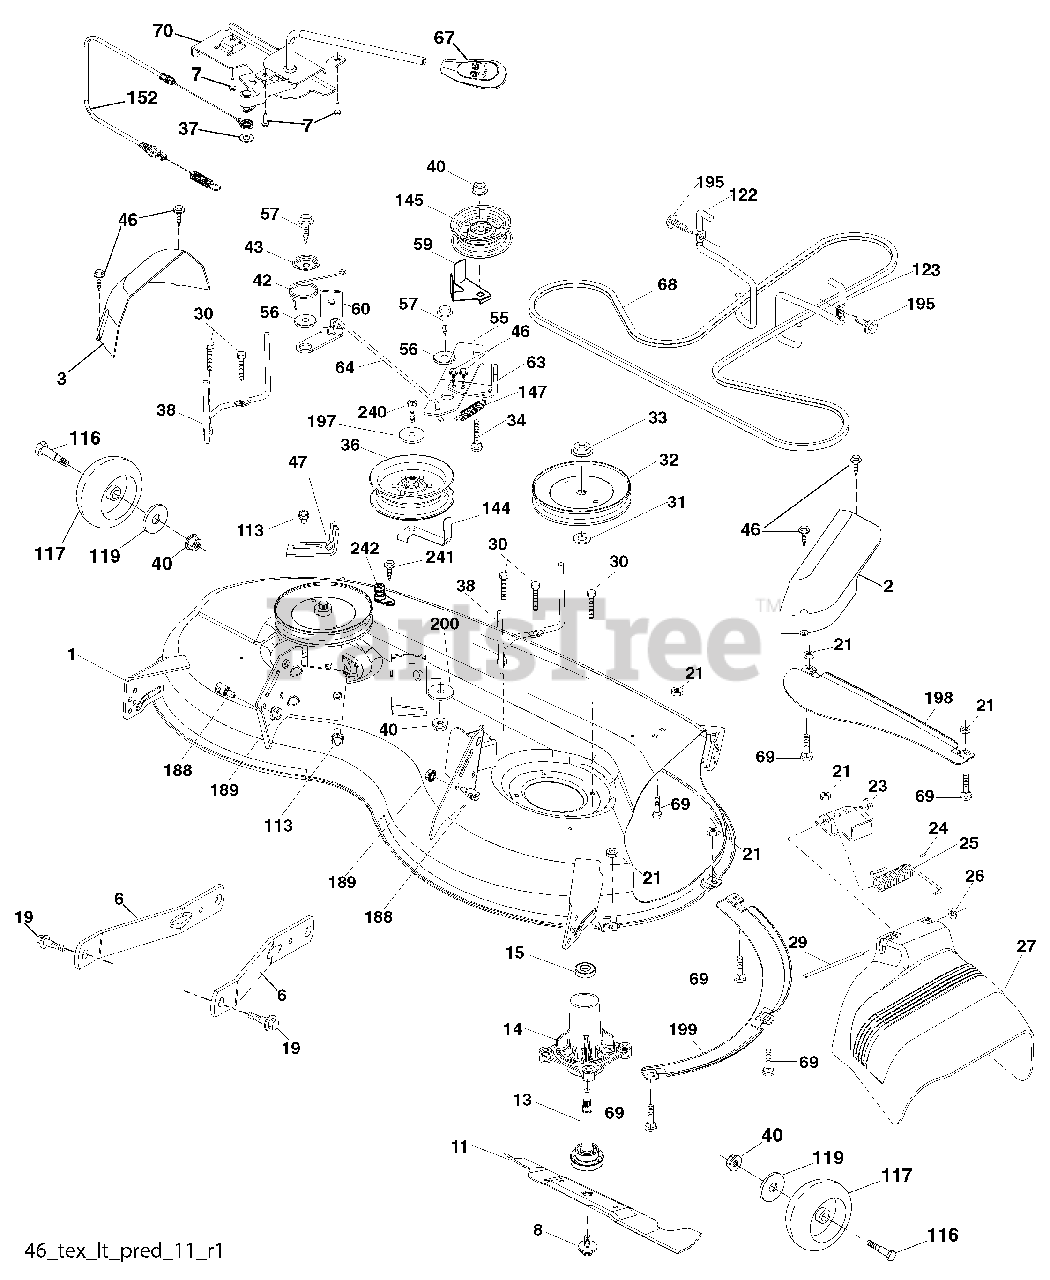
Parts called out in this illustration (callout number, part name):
1	Mower Housing
2	Cover Mandrel RH
3	Cover Mandrel LH
6	Arm Suspension
7	Screw # 10 x 0.750
8	Bolt/Washer asm 7/16-20 unf
11	Blade Mower Hi Lift
13	Shaft Assembly, Mandrel
14	Housing, Mandrel
15	Bearing, Ball, Mandrel
19	Bolt, Shoulder
21	Nut
23	Bracket, Deflector
24	Cap, Sleeve
25	Spring, Torsion, Deflector
27	Shield, Deflector
29	Rod, Hinge
30	Screw Thdrol Rolling Wsh Hd
31	Washer, Spacer
32	Pulley, Mandrel
33	Nut, Toplock, Flanged
34	Bolt Carr Sh. 3/8-16 x 1-1/2 Gr. 5
36	Pulley, Idler, Flat
37	Washer 13/32 x 13/16 x 16 Ga.
38	Keeper Belt Mandrel
40	Nut, Lock Flg. 3/8-16 unc
42	Spring Torsion Brake
43	Spring Torsion Retainer
47	Bracket Clutch Cable
55	Arm, Idler
56	Spacer, Retainer
57	Screw Hexwsh Thd 3/8-16 x 1
59	Guard, Tuv Idler (94)
60	Arm Brake Mower LH
63	Arm Brake Mower
64	Linkage Brake
67	Handle, Clutch Cable
68	V-Belt
69	Bolt
70	Clutch Asm. Cable
113	Screw 5/16-18
116	Bolt, Shoulder
117	Wheel, Gauge
119	Washer 13/32 x 1-1/4 x 12 Ga.
122	Keeper Belt Eng. LH
123	Keeper Belt Eng. RH
144	Keeper Belt
145	Pulley Idler
147	Spring Return
152	Cable Clutch Manual w/Spr.
188	Stud Fastener
189	Nut Lock Hex Flange
195	Screw 3/8-16 x 3/4
197	Washer 13/32 x 13/16 x 12 Ga.
198	Baffle Center Front
199	Baffle Front RH
200	Washer 13/32 x 1 x 1/2 11 Ga.
240	Bolt 3/8-16 unc x 2-1/4 Gr. 5
242	Washout Port
